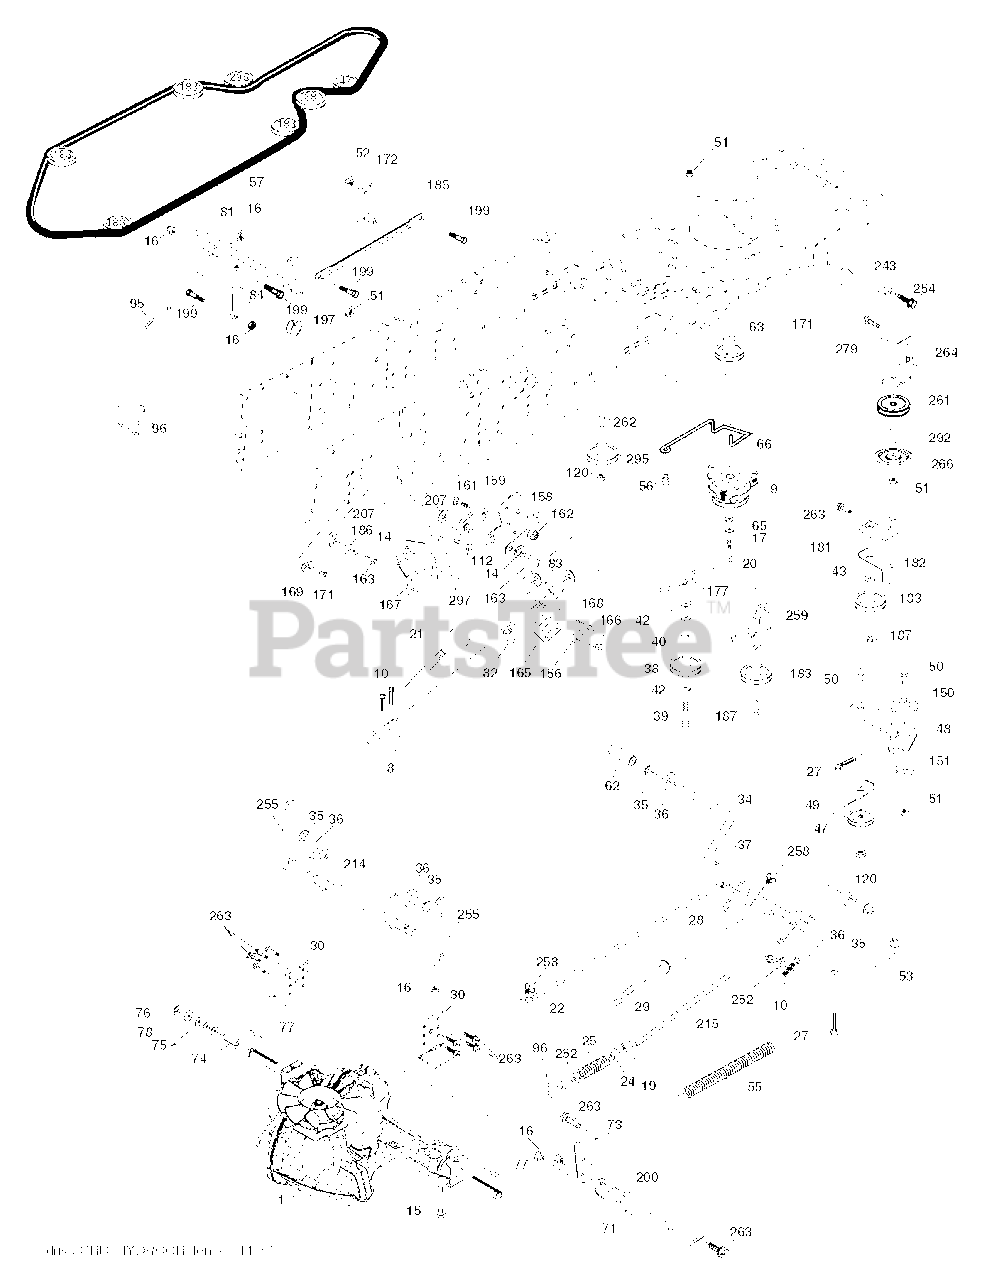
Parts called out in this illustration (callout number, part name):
8	ROD SHIFT FENDER ADJUST LT
10	PIN COTTER
14	LOCKWASHER
15	BOLT HEX 5/16-18 GR 5
16	NUT.71038.31-18.HEX.NYLOCK
17	LOCKWASHER
19	NUT
20	BOLT HEX 7/16-20X4-1/4"
21	PISTOL KNOB
24	NUT
27	COTTER PIN
28	ROD, PARKING BRAKE
29	PLUNGER CAP
30	BRKT, TRNSXLE MNT 20"
34	SHAFT, FOOT PEDAL
35	BEARING.NYLON
36	WASHER LT
37	DRIVE PIN
38	PULLEY.FLAT
42	WASHER
47	IDLER PULLEY
48	BELLCRANK, CLUTCH
49	RETAIN BELT
50	BOLT.3/8-16X1.50
51	LOCKNUT
52	LOCKNUT
53	LINK.CLUTCH.7.66.2005
55	SPRING, RETURN LT
56	SCREW.3/8-16
62	PEDAL COVER T
66	KEEPER BELT ENGINE
71	STRAP TORQUE LH HYDRO
73	STRAP TORQUE RH HYDRO
74	SPACER AXLE
76	E-RING LT
77	SQUARE KEY
81	SHAFT ASSY
82	SHIFT SPRING
83	WASHER
96	RETAINER M
112	WASHER LT
120	NUT LOCK FLG 3/8-16 UNC
150	BUSHING.BELLCRANK.GRD.DR
151	WASHER 12/32X2X10GA
156	WASHER.SRRTD.5/16
158	BRACKET
159	HUB.SHIFT
161	BOLT
162	NUT.CROWNLOCK.1/4
165	RP BRACKET
167	BRACKET
168	BOLT.SHOULDER.5/16-18X
169	PLATE.FASTENING.CROSS.SHAFT
183	PULLEY.V-IDLER.
187	BOLT.5/16-18X1.25
197	NYLINER SNAP 5/8" ID
199	BOLT SHOULDER 5/16-18 UNC
200	BOLT
207	WASHER NYL
243	BRACKET, ANTI-ROTATION
254	SCREW 3/8-16X1
258	CLIP RETAINER
261	FLAT IDLER PULLEY
263	SCREW, 3/8-16X3/4
264	BRACKET.IDLER
279	BOLT
295	PULLEY IDLER COMPOSITE
297	SCREW LT.3/8-46X5/8
